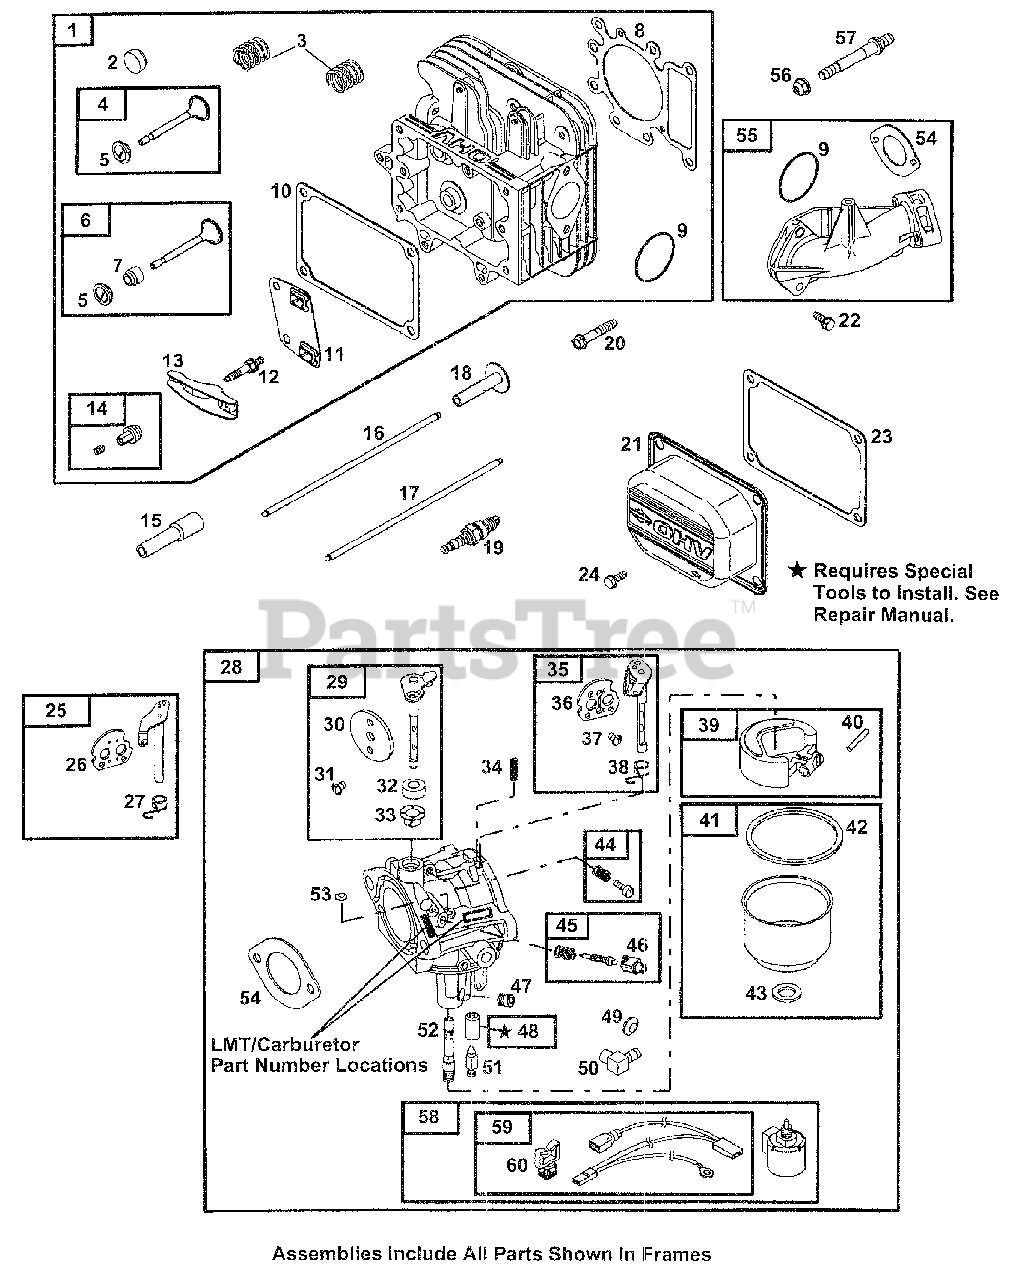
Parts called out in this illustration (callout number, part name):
1	Cylinder Head
3	Valve Spring
4	Exhaust Valve
5	Valve Retainer
6	Intake Valve
7	Valve Seal
8	Cylinder Head Gasket
9	O-Ring Seal (Intake Manifold)
10	Rocker Cover Gasket
11	Push Rod Guide
12	Stud (Rocker Arm)
13	Rocker Arm
14	Rocker Arm Adjuster
15	Sparkplug Boot
16	Pushrod (Intake)
17	Pushrod (Exhaust)
18	Valve Tappet
19	Sparkplug
20	Screw (Cylinder Head)
21	Rocker Arm Cover
22	Screw (Intake Manifold)
23	Rocker Cover Gasket
24	Screw (Rocker Arm Cover)
25	Choke Shaft Kit (LMT 153, 154)
26	Choke Valve (LMT 153, 154)
27	Spring/Seal Assy (Choke A Matic)
28	Carburetor
29	Throttle Shaft Kit
30	Throttle Valve
31	Screw (Throttle Valve)
32	Throttle Shaft Seal
33	Throttle Shaft Bushing
34	Screw (Drive Cap)
35	Choke Shaft Kit (LMT 155, 156)
36	Choke Valve (LMT 155, 156)
37	Screw (Choke Valve)
38	Spring/Seal Assy (LMT 155, 156)
39	Carburetor Float
40	Float Hinge Pin
41	Float Bowl
42	Float Bowl Gasket
43	Sealing Washer
44	Idle Speed Kit
45	Idle Mixture Kit
46	Limiter Cap
47	Main Jet (Standard)
48	Inlet Seat (Gravity Feed)
49	Welch Plug
50	Hose Connector
51	Float Needle Valve
52	Carburetor Nozzle
53	Welch Plug
54	Intake Gasket
55	Intake Manifold
56	Nut (Carburetor)
57	Stud (Carburetor)
58	Fuel Solenoid
59	Wiring Harness
